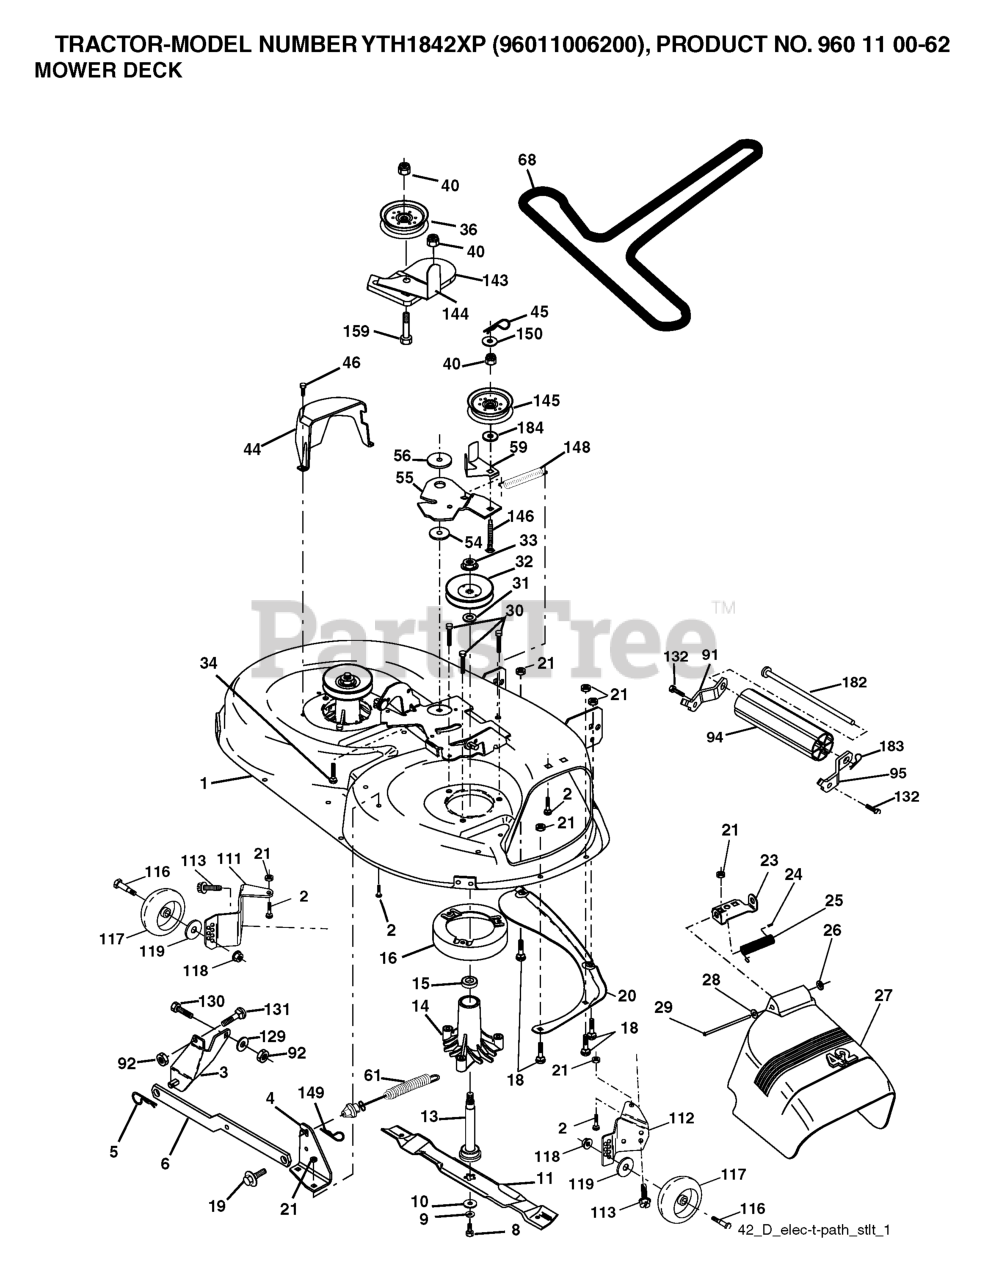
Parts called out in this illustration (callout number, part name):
1	42" DECK KIT
2	RP BOLT 5/16-18 X3/4 ZN/YEL GR
3	BRKT ASM SWAY BAR
4	BRACKET SWAY BAR 42" DECK
5	RETAINER-SPRNG RB
6	BAR SWAY DECK
8	BLADE BOLT
9	LOCKWASHER
10	WASHER.BLADE
11	42" HI-LIFT BLADE
13	SHAFT ASM VENT
14	HOUSING.MANDREL.VENTED (MACHD)
16	STRIPPER.MANDREL.ROUND.BLACK
18	BOLT
19	BOLT SHD 5/16-18
20	BAFFLE.VORTEX
21	LOCKNUT
23	BRKT, DEFL. MOWER
24	CAP-SLEEVE LT
25	SPRING TORSION
26	NUT PUSH M
27	SHIELD DEFLECTOR
28	Washer 11/32 x 5/8 x 16 Ga SD
29	ROD.HINGE
30	SCREW, WASHER HEAD
31	WASHER.SPACER.MANDREL
32	PULLEY/MANDREL
33	NUT, FLG TOPLOCK 9/16"
34	BOLT.3/8-16X1.50
36	FLAT IDLER PULLEY
40	NUT LOCK FLG 3/8-16 UNC
44	GUARD MANDREL LH BLACK
45	RETAINER M
46	SCREW.1/4-20X5/8
55	ARM IDLER 42" MOWER LT/YT
56	SPACER.RETAINER.MOWER
59	GUARD, BELT
61	SPRING EXT ELEC CLUTCH
68	V-BELT PRIMARY 42"
91	BRACKET ASM NOSEROLLER LH
92	NUT
94	NOSE ROLLER
95	BRACKET ASM NOSEROLLER RH
111	BRACKET, WHEEL
112	BRACKET, WHEEL
113	BOLT.5/16HEX.WHS.HD
116	BOLT M
117	WHEEL.GAUGE.STANDARD
118	LOCKNUT
119	WASHER.5/16.FLAT.STE.STD.
129	WASHER
131	BOLT D
132	SCREW, 3/8-16X3/4
143	BRACKET, ARM IDLER
144	DNO KEEPER.BELT.42".CLUTCH.CBL
145	PULLEY
146	BOLT, CARRIAGE IDLER BLACK
148	IDLER RETURN SPRING
149	SPRING.RETAINER.YELLOW.ZINC
182	ROD ROLLER NOSE STANDARD
183	SPRING RETAINER
184	WASHER
